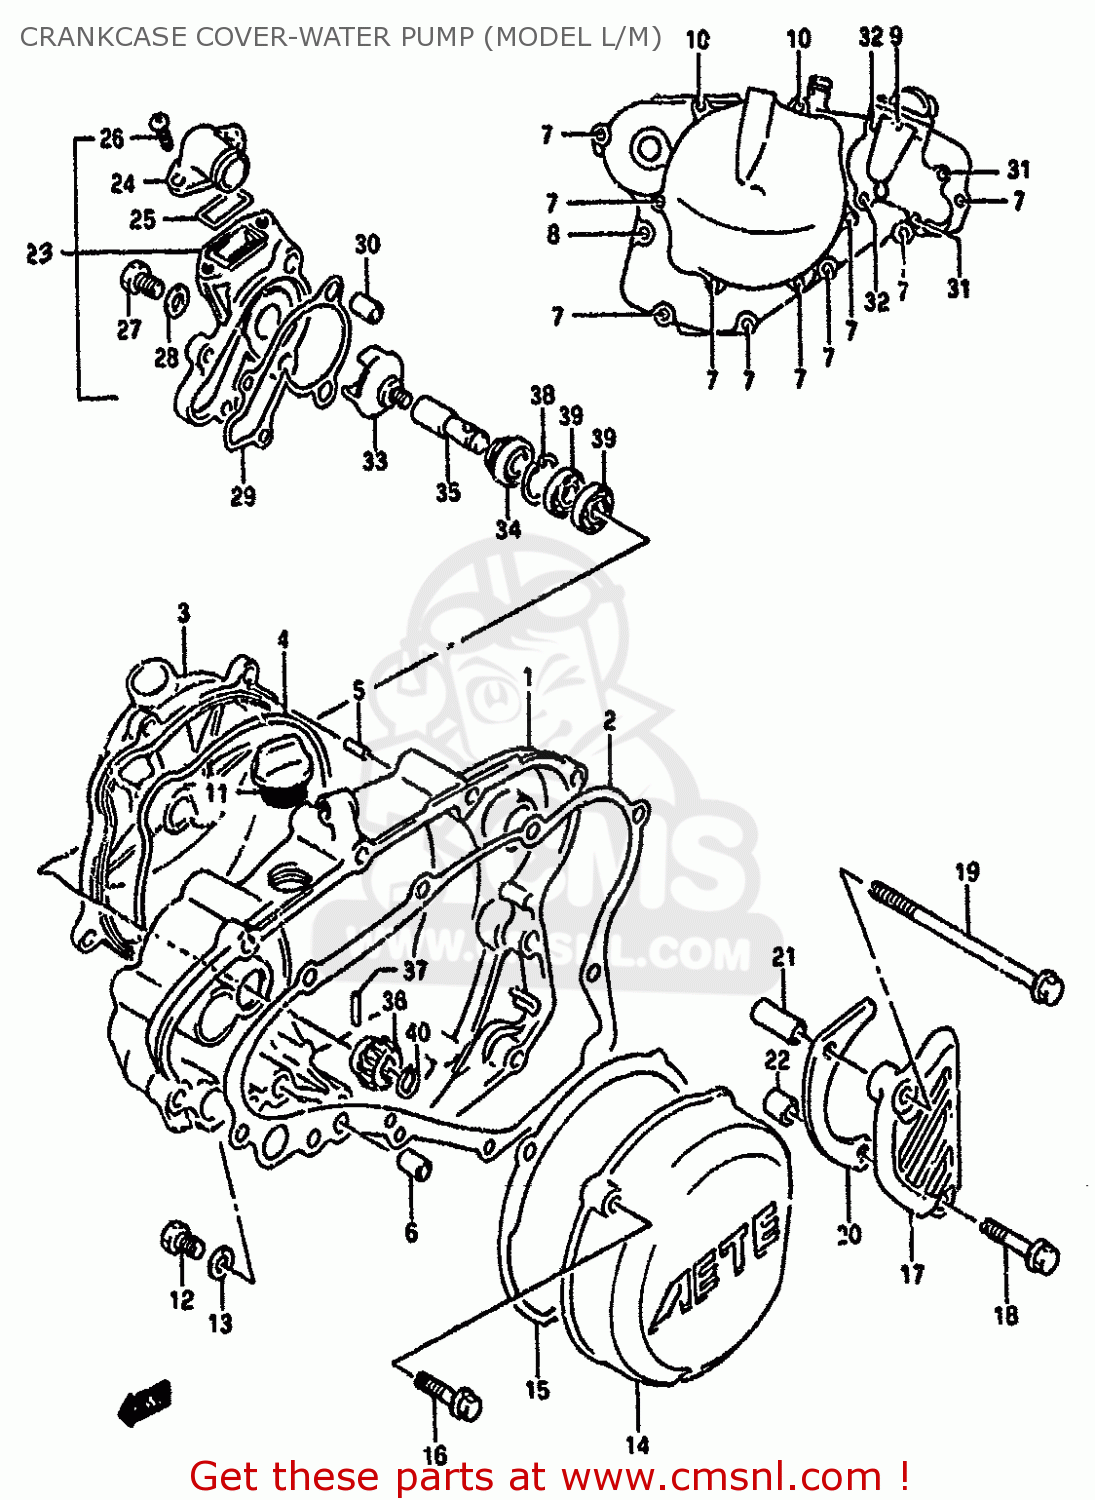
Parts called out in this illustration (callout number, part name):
1	COVER,CLUTCH
2	GASKET,CLUTCH COVER (NAS)
3	COVER,CLUTCH,OUTER
4	O RING,CLUTCH COVER OUTER
5	PIN
6	PIN
7	BOLT
8	BOLT
9	BOLT
10	BOLT
11	PLUG SET
12	SCREW(6X10)
13	GASKET(6.2X11X1).2 (NAS)
14	COVER,MAGNETO
15	GASKET,MAGNETO COVER (MCA)
16	BOLT
17	COVER,SPROCKET
18	BOLT
19	BOLT(6X105)
20	PLATE,FR CHAIN GUIDE
21	SPACER(6.5X10.5X25)
22	SPACER(6.5X10.5X12)
23	CASE ASSEMBLY,WATER PUMP
24	CONNECTOR
25	O RING,WATER PUMP CONNECTOR
26	SCREW
27	BOLT,BLEEDER
28	GASKET (NAS)
29	GASKET,WATER PUMP CASE (NAS)
30	PIN
31	BOLT
32	BOLT
33	IMPELLER,WATER PUMP
34	SEAL,WATER PUMP OIL
35	SHAFT,WATER PUMP
36	GEAR,WATER PUMP DRIVEN
37	PIN(3X13.8)
38	CIRCLIP
39	BEARING
40	CIRCLIP
